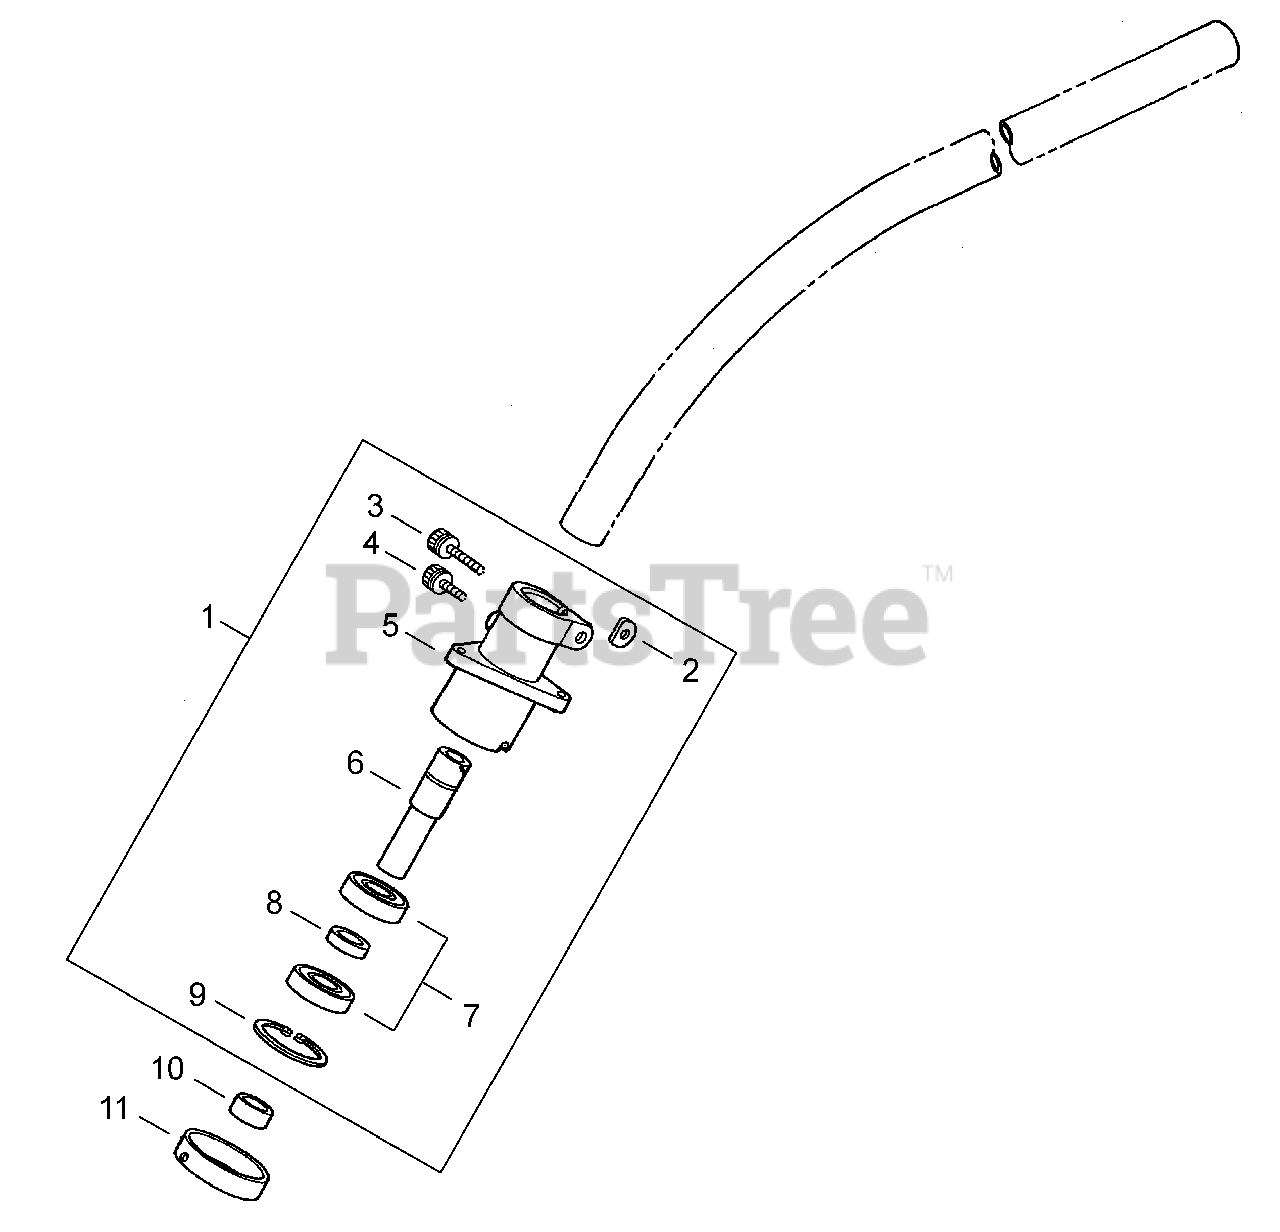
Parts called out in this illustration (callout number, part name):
1	MAIN PIPE ASSY
2	PIPE, MAIN
3	LABEL, CAUTION (NON-BLADE CAPABLE)
5	DRIVESHAFT - FLEXIBLE
6	LABEL, HANDLE
